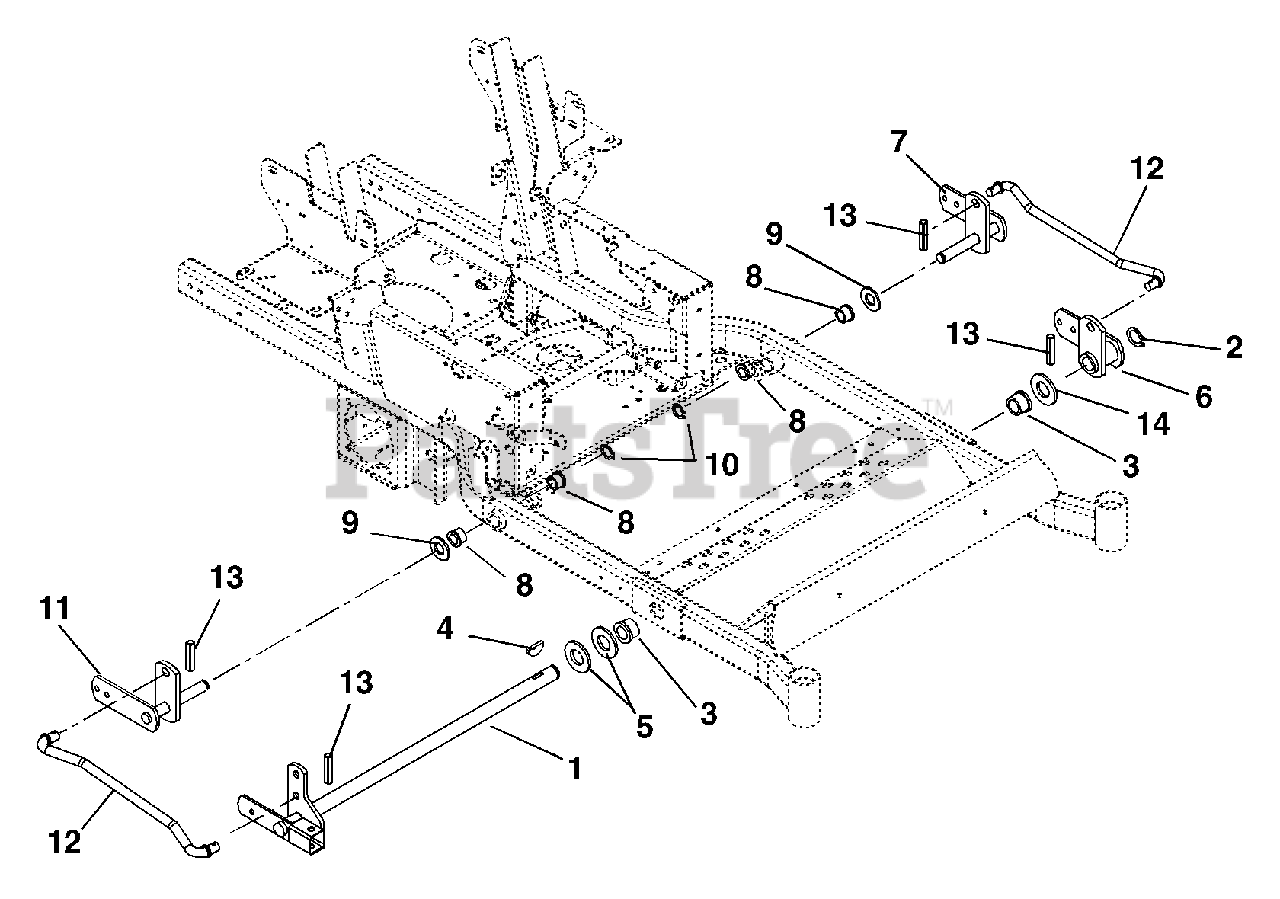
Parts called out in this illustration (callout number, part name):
1	Weldment, Lift Arm
2	Ring, Retaining External 1.00 x .078
3	Bushing, Flange Nylon 1.020 x 1.385 x .75 x 1.75
4	Key, Woodruff .25 x 1.00
5	Washer, Flat Steel 1.063 x 2.00 x .134
6	Lift Arm - Front
7	Lift Arm Shaft - Left Hand
8	Bushing, Flange Nylon .762 x 1.0 x .580 x 1.48
9	Washer, Hardened Steel .758 x 1.23 x .031
10	Ring, Retaining External .689 x .077
11	Lift Arm Shaft - Right Hand
12	Rod, Lift Assist
13	Pin, Roll .25 x 1.25
14	Washer, Hardened Thrust 1.00 x 1.55 x .03
